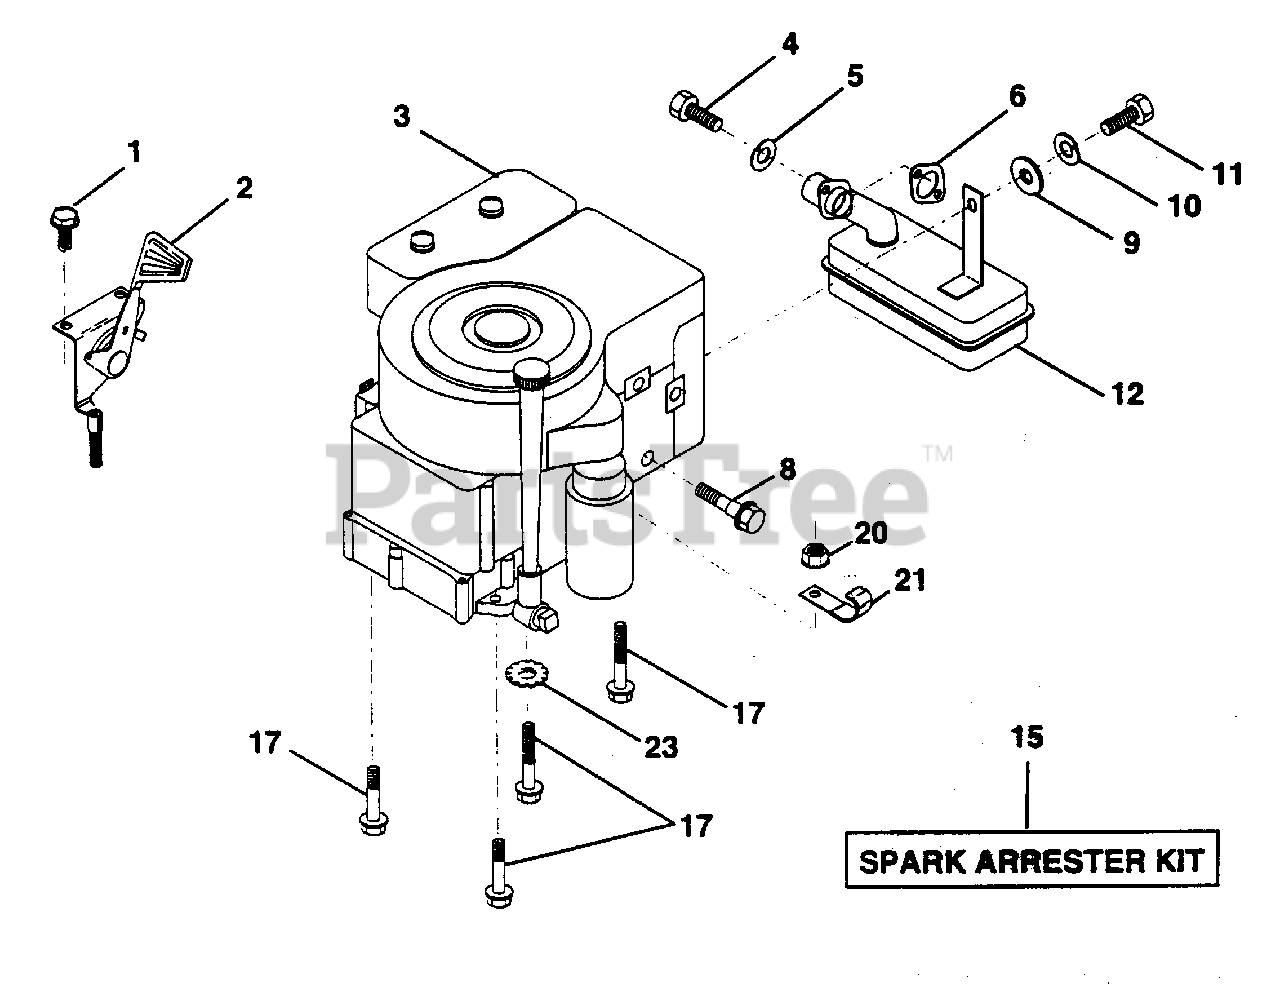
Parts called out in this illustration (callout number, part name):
1	Screw, Hex Head, Thread Cutting 1/4-20 x 1/2
2	Control, Throttle
4	Screw, Hex Cap 5/16-18 x 3/4
5	Washer, Lock, Heavy Helical Spring 5/16
6	Gasket, Exhaust
8	Bolt, Shoulder 5/16
9	Washer 5/16 x 3/4 x 10 Gauge
10	Washer, Lock, Heavy Helical Spring 1/4
11	Bolt, Hex Hd. 1/4-20 x 3/5
15	Arrester, Spark (Optional Equipment)
17	Screw, Hex Washer Head, Thd., Roll. 3/8-16 x 1-1/2
20	Nut, Keps, Hex 3/8-16
21	Clip, Fuel Line
23	Washer Lock Ext Tooth 3/8
